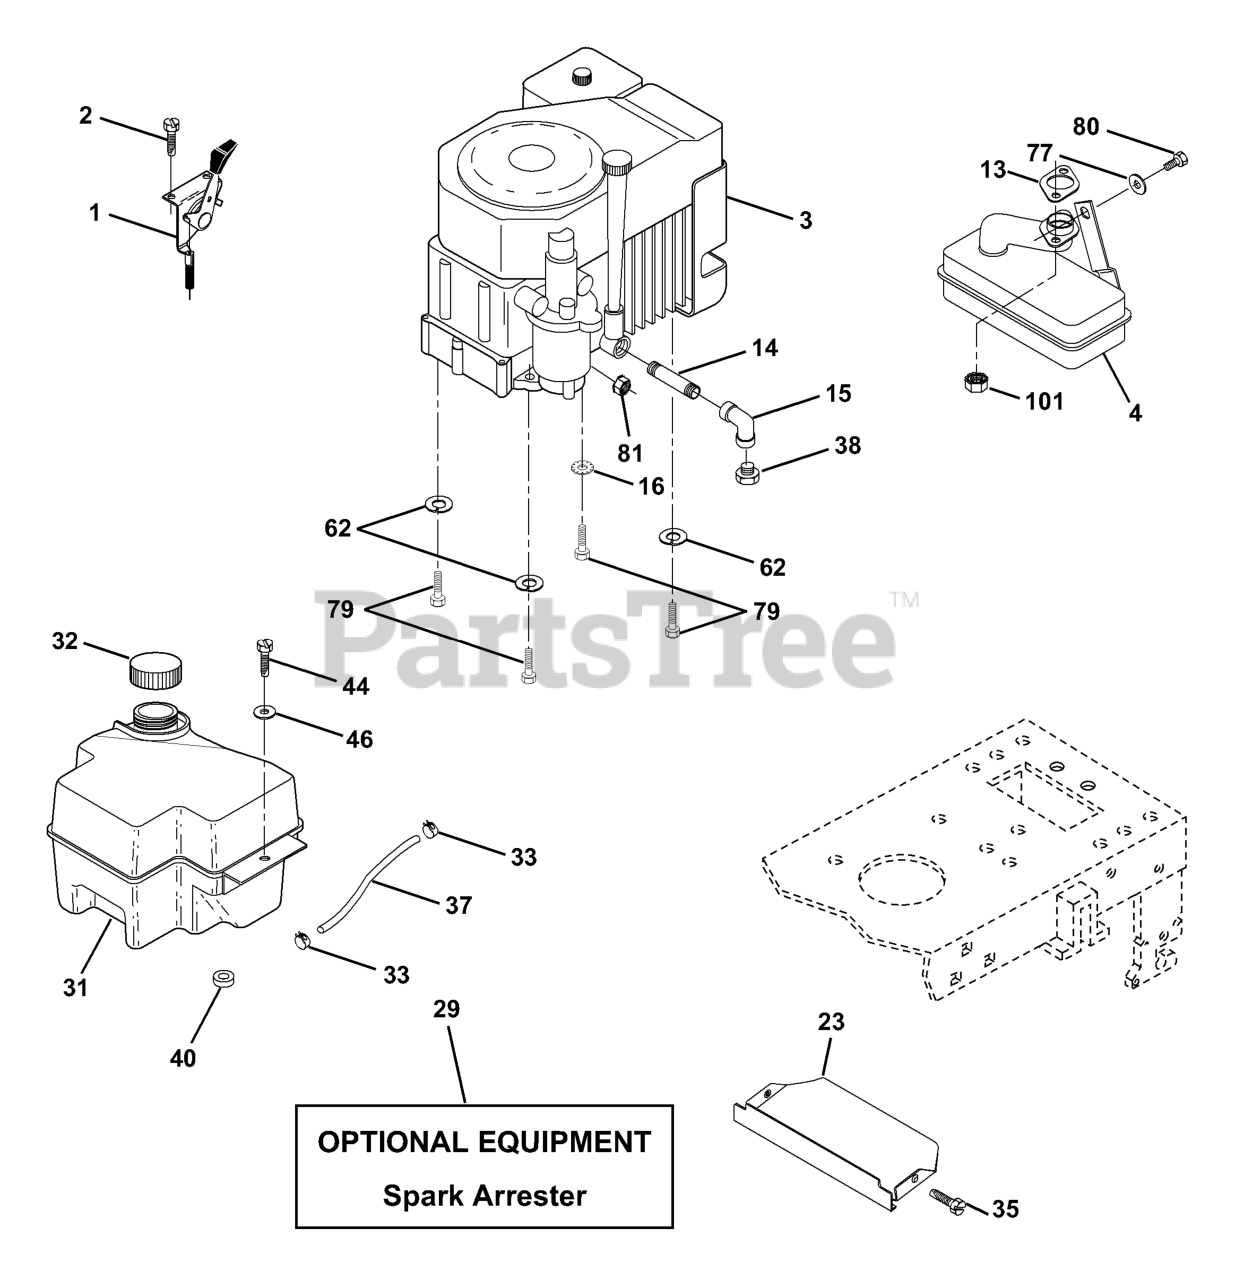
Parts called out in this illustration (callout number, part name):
1	CONTROL SWITCH 27 LH
2	SCREW LT
3	Engine Kohler
4	MUFFLER.KOHL.CV.SINGLE.W/PORT
14	Nipple Pipe 3/8 Npt X 3-1/2
15	ELBOW
16	WASHER EXT TOOTH LOCK 5/16
29	KIT.SPARK ARRESTOR 794945 B&S
31	FUEL TANK
32	FUEL CAP
33	HOSE CLAMP
35	SCREW.THDROL.5/16-18X3/4.TTY
37	LINE.FUEL.20
38	Plug Oil Drain
40	BUSHING.SNAP.NYL.BLK.
44	SCREW HEX CRT
46	WASHER
62	WASHER.LOCK.HVY.HLCL.SPR.5/16
77	WASHER
79	BOLT, HEX
80	Bolt Hex Hd 5/16-18 UNC x 1/2
81	NUT FLANGE 1/4-20 STARTER NUT
